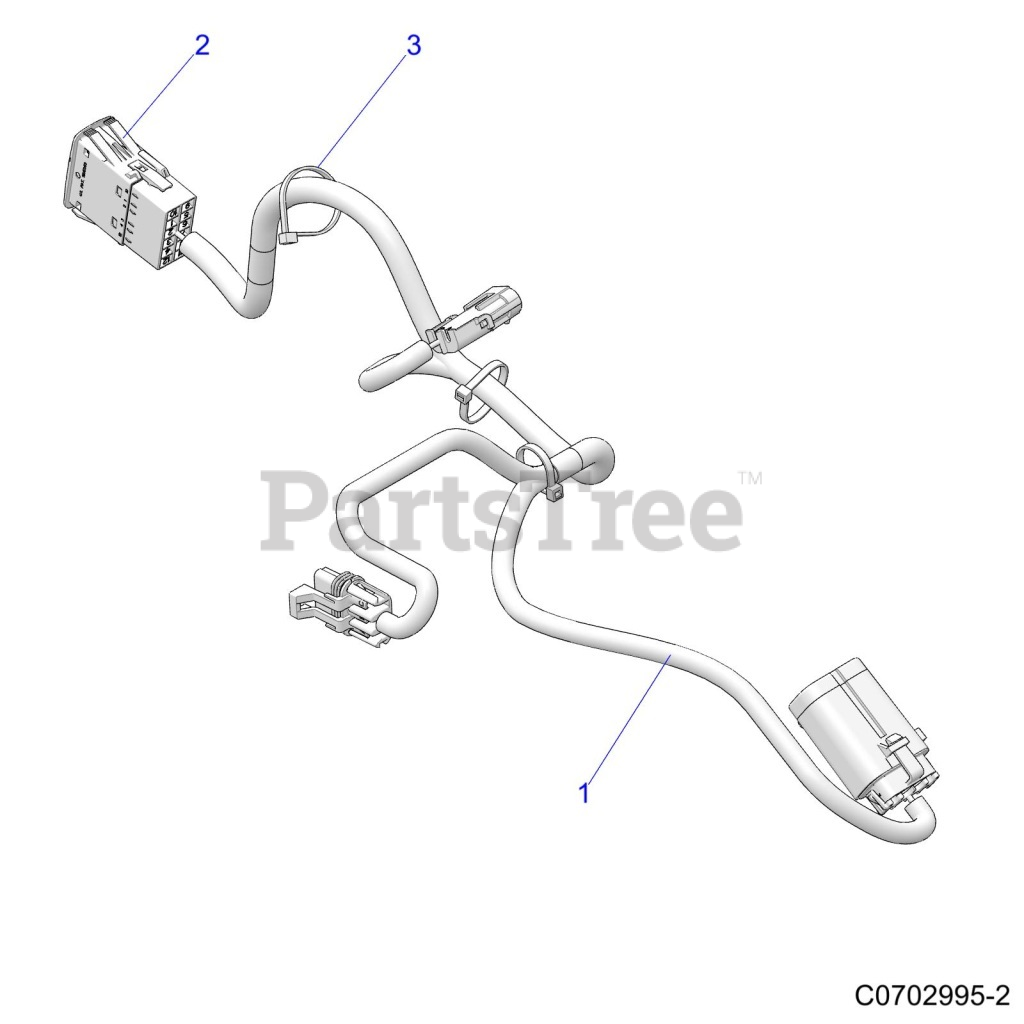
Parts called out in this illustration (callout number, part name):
1	HARNESS-BOX LIFT,ZS
2	SWITCH-BOX LIFT
3	CABLE TIE (10)
